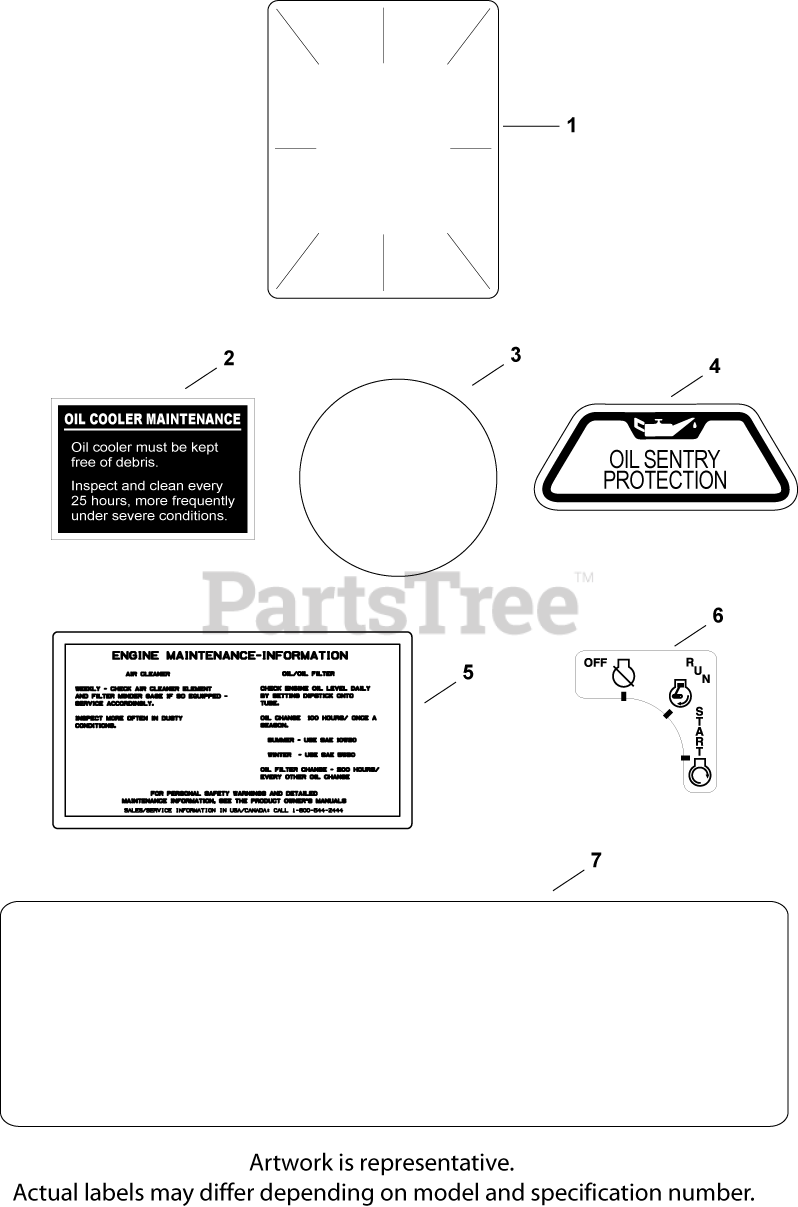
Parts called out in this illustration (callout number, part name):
1	DECAL, CLEAR LAMINATE USE 25 113 70-S
2	DECAL, OIL COOLER - (#DSC)
3	LABEL, (ROUND KOHLER GOLD)-USE 24 113 18
4	DECAL, OIL SENTRY - (#DSC)
5	DECAL, AIR CLEANER - (#DSC)
6	DECAL, KEY SWITCH
7	DECAL, 25 HP
